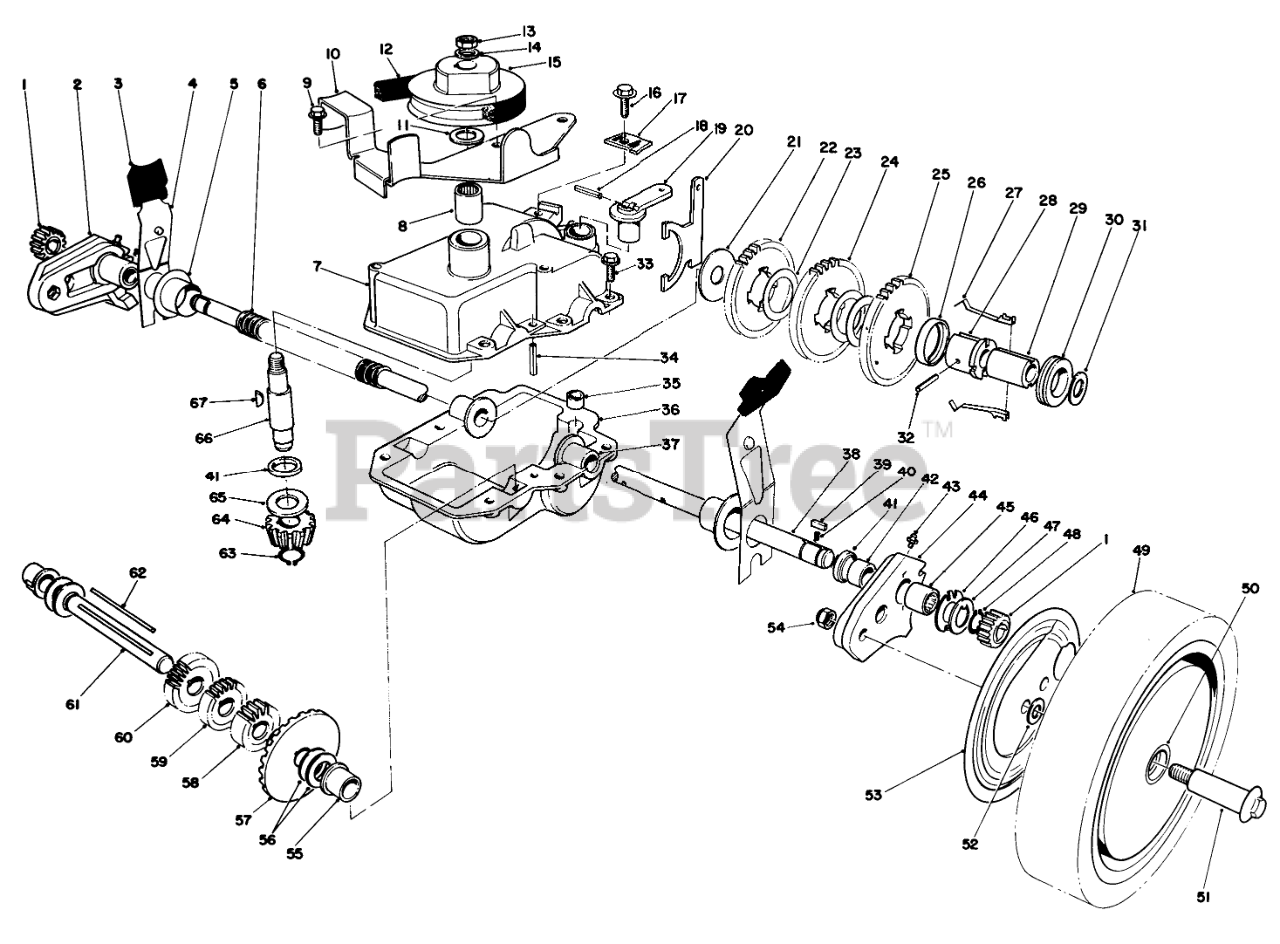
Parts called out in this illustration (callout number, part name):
1	GEAR-PINION
2	Pivot Arm Assembly-R.H. (Incl. Ref. #41-43 & 45)
3	KNOB-ARM
4	SPRING ARM ASM SP
5	CAP-END
6	CONDUIT-CONVOLUTED, SPLIT
7	Case-Upper
8	BEARING
9	SCREW
10	BELT GUIDE BRKTB
11	WASHER-THRUST
12	V-BELT
13	NUT-HEX
14	WASHER-FLAT
15	PULLEY
16	SCREW-HWHTF
17	Cable Clamp
18	PIN-COIL
19	LEVER-SHIFT
20	Shift Yoke
21	WASHER
22	GEAR-38T
23	WASHER
24	GEAR-42T
26	RETAINER-KEY
27	KEY-SHIFT
28	SLEEVE-GEAR
29	SLEEVE
30	COLLAR-SHIFT
31	WASHER-PLAIN
32	PIN-SPRING
33	SCREW-HWHTF
34	ROLL PIN 3/16 X 1 IN
35	BUSHING-YOKE
36	LOWER GEAR CASE CAST
37	Bushing-Output Shaft
38	Output Shaft
39	KEY RECTANGULAR
40	SPRING-COMPRESSION
42	BUSHING
43	FITTING-GREASE
44	Pivot Arm Assembly-L.H. (Incl. Ref. #41-43 & 45)
45	BEARING-ROLLER
46	INNER THRUST WASHER
47	WASHER-THRUST, OUTER
48	RING-RETAINING
49	Wheel, Tire & Gear Assembly (Incl. Ref. #50)
50	BUSHING
51	WHEEL BOLT
52	WASHER
53	WHEEL COVER
54	Nut
55	BUSHING
56	WASHER-THRUST
57	BEVEL GEAR
58	GEAR-12T
59	GEAR-14T
60	GEAR-18T
61	INTERMEDIATE SHAFT
63	RING-RETAINING
64	PINION-BEVEL
65	WASHER-THRUST
66	INPUT SHAFT
67	KEY-WOODRUFF
